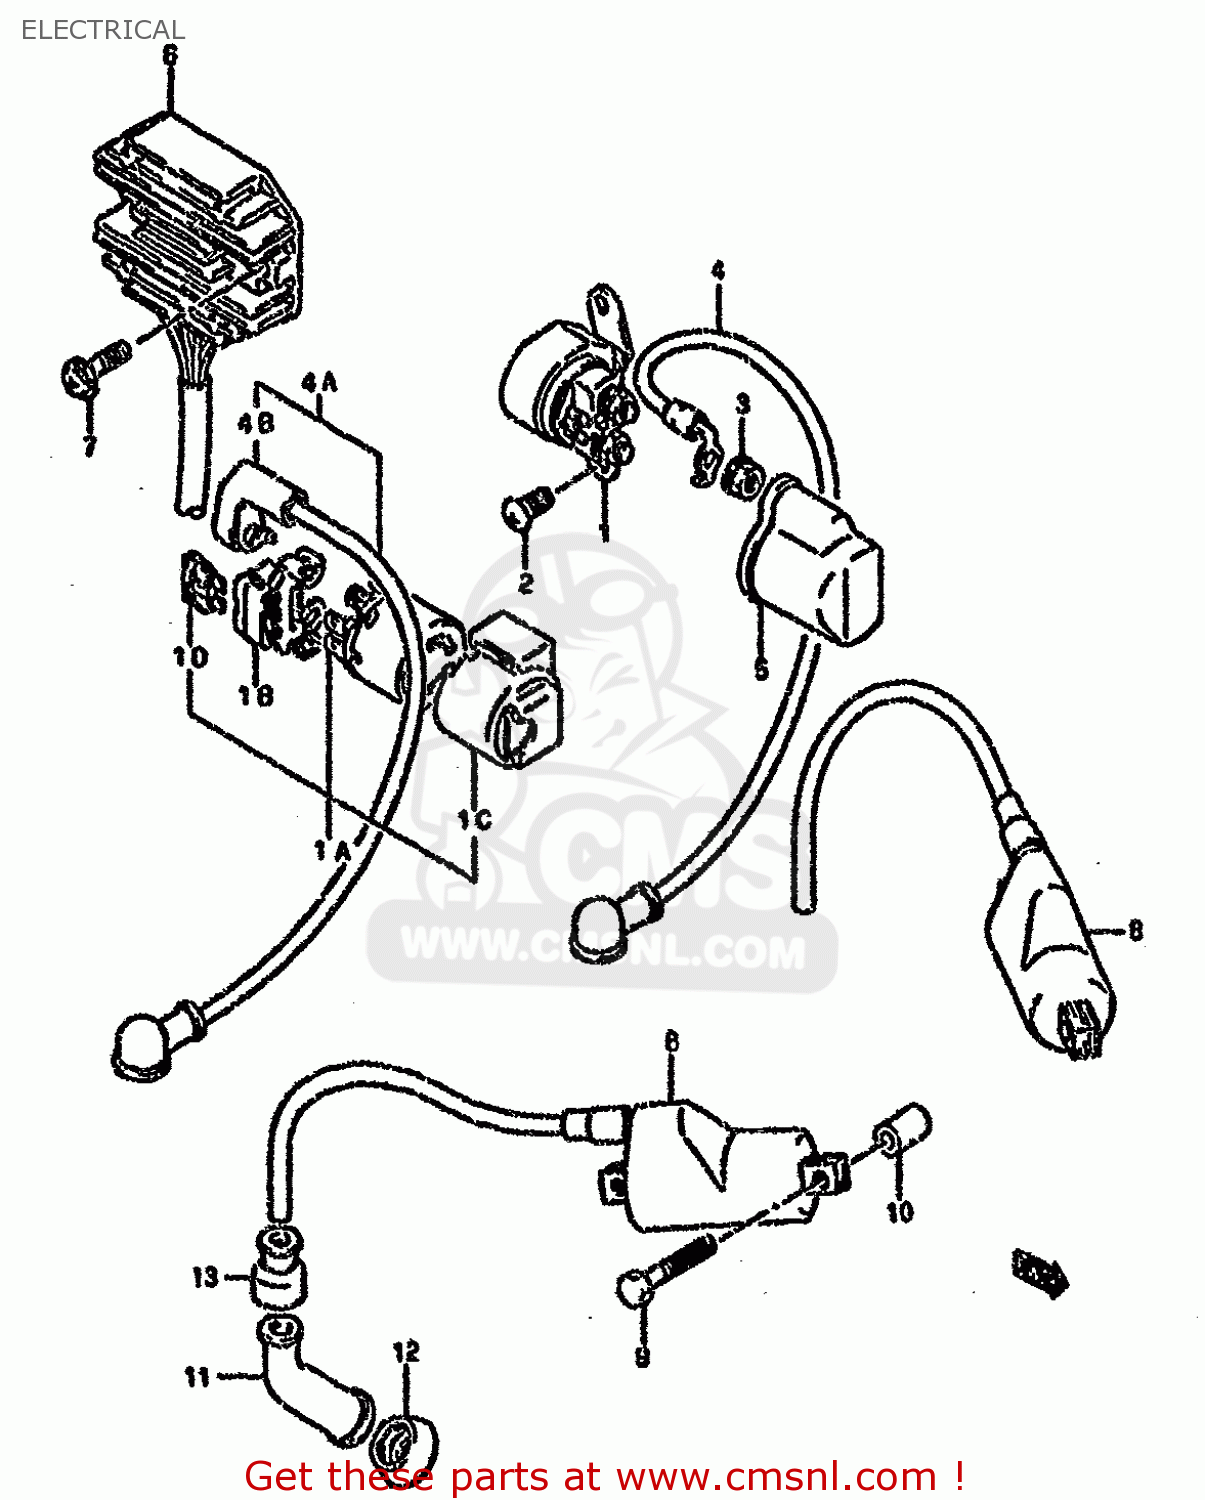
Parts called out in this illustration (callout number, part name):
1	RELAY ASSY,STARTING MOTOR
1A	RELAY ASSY,STARTING MOTOR
1B	TERMINAL,RELAY
1C	BRACKET,STARTING MOTOR RELAY
1D	FUSE(20A)
2	SCREW
3	NUT
4	WIRE,STARTER MOTOR LEAD
4A	WIRE,STARTER MOTOR LEAD
4B	CAP,STARTER RELAY TERMINAL
5	CAP,STARTER RELAY
6	RECTIFIER ASSY
7	SCREW
8	COIL ASSY,IGNITION
9	BOLT
10	SPACER(6.2X12X18)
11	CAP,SPARK PLUG
12	SEAL,SPARK PLUG CAP
13	SEAL,HIGH TENSION CORD
